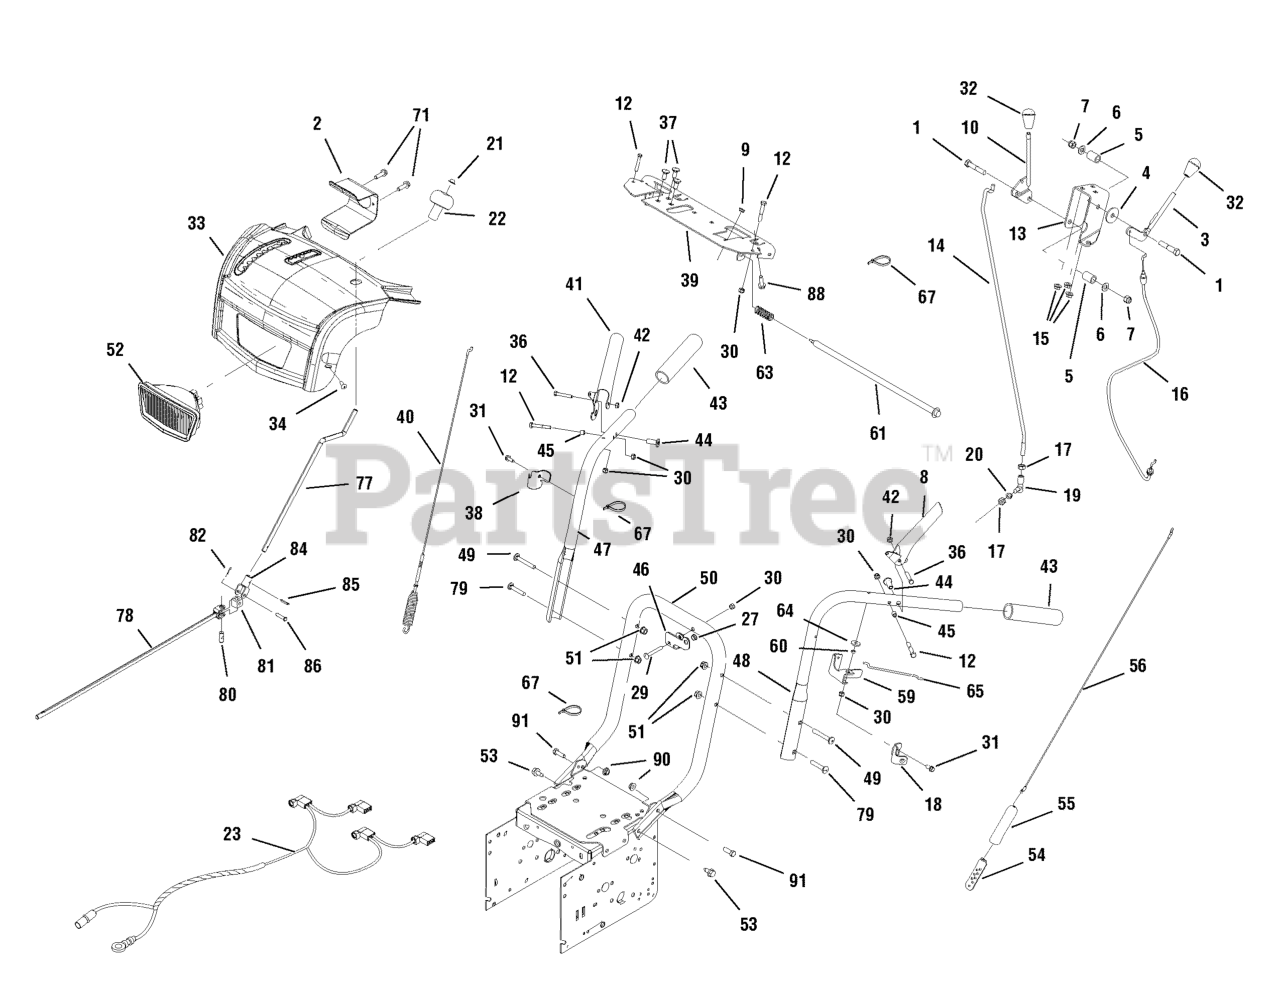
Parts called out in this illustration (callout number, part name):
1	CAPSCREW-HEX. 375 - 16x2.00
2	BRACKET, LIGHT MOUNT
3	LEVER-DEFLECTOR CONTROL
4	WASHER, 3/8
5	SPRING- COMPRESSION .509 x .75 2
6	WASHER- O. 375 O. 4 1 x 0.8 1 x .06
7	NUT -HEXLK ESNA LT . 38- 16NC3B
8	LEVER-CLUTCH LH PLASTISOL DIP
10	ROD & BRACKET ASSEMBLY, SPEED
12	CAPSCREW-HEX .250- 20 x 1 . 75
13	BRKT- SPEED & DEFLECTOR CONTROL
14	ROD-LINK SPEED CONTROL
15	NUT-HEX FLANGE . 3 12- 18 WHIZ
16	CABLE ASSEMBLY-DEFLECTOR
17	NUT-HEX . 3 12- 24 YELLOW
18	MNTG BRKT - DASH LH
19	BALLJOINT-STEEL
20	LOCKWASHER - SPRING . 312 BLK
21	NUT, PUSH PAL STUD CAPPED 3/8
22	KNOB, SPINNER
23	WIRING HARNESS
29	CARRIAGE BOLT, 1/4-20 x 2
30	NUT-HEX LOCK ESNA .250-20
31	SCREW-HEX WSHR HD TT .25- 20x. 62
33	COVER-PANEL ASS'Y
34	SCREW-PAN HD TR x . 250-20 x .75 TAP
36	CAPSCREW- HEX .2 50 -20 x 1 .50
37	CARRIAGE BOLT . 31 2- 18 x . 75
38	MNTG BRKT - DASH RH
39	SUPPORT-DASH PANEL
40	CABLE & SPRING ASSEMBLY
41	GRIP-CLUTCH-RH PLASTISOL
42	NUT-HEX CTR LOCK. 250- 20 BLK
43	FOAM GRIP
44	SPACER- HANDLE-YELLOW
45	SPACER- 0.265x0.370x.330
46	BRACKET, ROD SUPPORT
47	HANDLE-UPPER RH
48	HANDLE-UPPER LH
49	BOLT-RD HD SO NK .312-18x2.25
50	HANDLE-LOWER
51	NUT-HEX FLANGE.312-18 ESNA
52	HEAD LIGHT ASSEMBLY
53	SCREW-HEX WSHR HD TT .31-18x.75
54	BRACKET-CABLE ADJ
55	BOOT-CONTROL SPRING
56	CABLE-DRIVE
59	BRACKET-FREE HAND CONTROL
60	SPACER-PWDR METAL YELLOW
61	ROD-FREE HAND CONTROL
63	SPRING-COMP.53x2.25 .059 WIRE
64	WASHER-.250.26x0.84x.12
65	ROD-HOLDDOWN
67	TIE-SELF LOCKING .184WDx7.31
71	SCREW, 10 X .62
77	CRANK ROD
78	CHUTE, CRANK
79	BOLT-RD HD SH SO NK .312-18x1.75
80	PIN, UNIVERSAL JOIINT
81	HOUSING, UNIVERSAL
82	PIN, COTTER
84	YOKE ADAPTER ASSEMBLY
85	PIN, HAIR
86	PIN, CLEVIS
88	SCREW, 1/4-15X3/4, Self-Tapping, BZ
90	NUT-HEX FLANGE .31-18 2-WAY LK
91	CAPSCREW, Hex Head, 5/16-18 x 1
